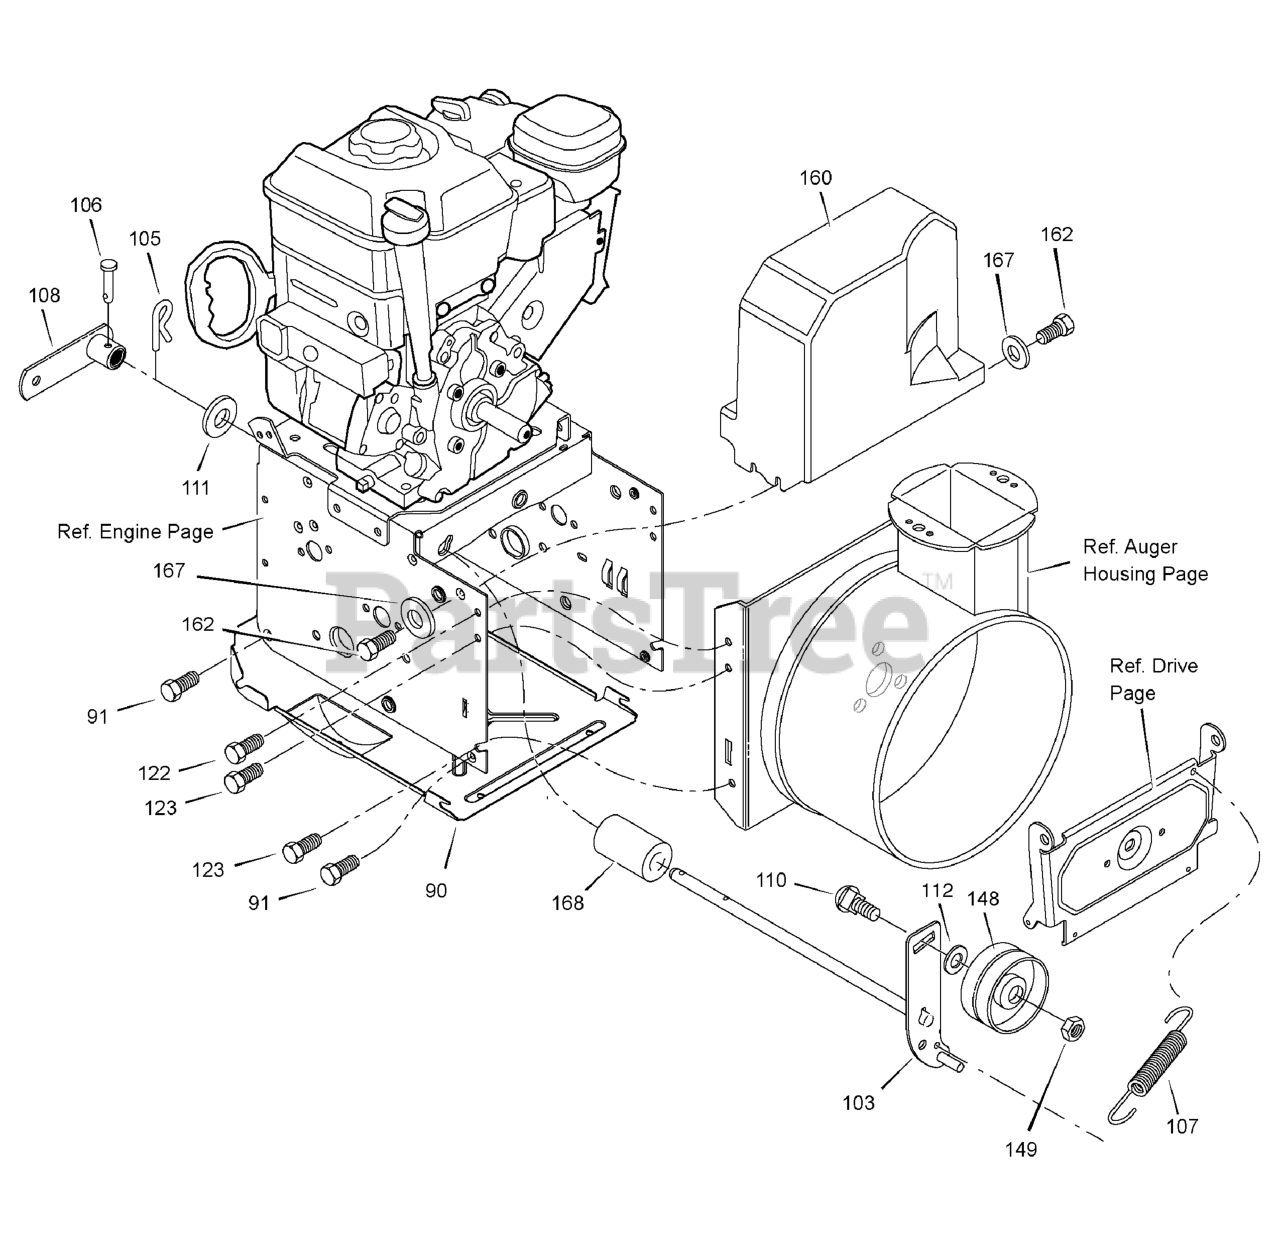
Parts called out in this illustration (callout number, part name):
90	COVER, BOTTOM
91	SCREW, 1/4-20 x 5/8
103	IDLER ASSEMBLY, Auger
105	PIN, Hair
106	PIN, Clevis
107	SPRING, Tension
108	ARM, Control
110	BOLT, Carriage, 3/8-16 x 1-1/4
111	WASHER, Flat
122	SCREW, Tap, 5/16-18 x 1/2
123	SCREW, Tap, 5/16-18 x 3/4
148	PULLEY, Idler
149	NUT, Jam, 3/8-16
160	COVER, Belt
162	SCREW, Tap
167	WASHER, Flat
168	SPACER, Auger Bracket
